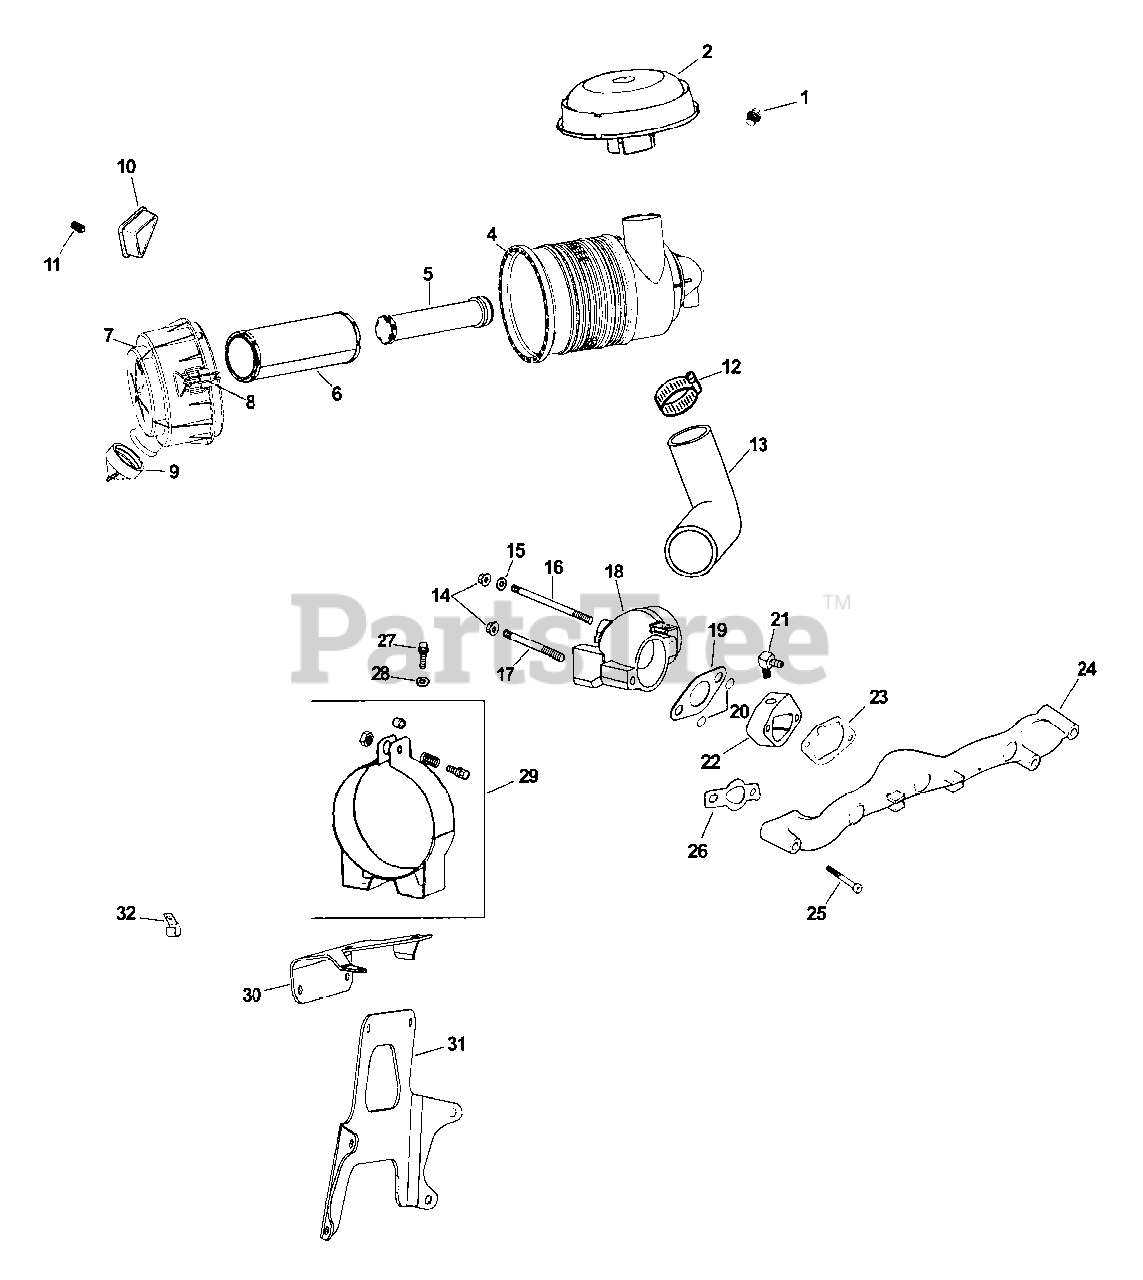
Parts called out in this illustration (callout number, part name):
2	Heavy Duty Air Cleaner Hood
4	Heavy Duty Air Cleaner Housing
5	Air Cleaner Element - Safety
6	Air Cleaner Element - Primary
7	Air Cleaner Cover Assembly
8	Clip
9	Dust Ejector Valve
10	Blower Housing Cover
11	Tapping Screw
12	Hose Clamp
13	Air Cleaner Hose
14	Hex Lock Nut (M6 x 1.0)
15	Copper Washer (1/4")
16	Stud (M6 x 1.0 x 180)
17	Stud (M6 x 1.0 x 40)
18	Elbow Adapter
19	Air Cleaner Adapter Gasket
21	Hose Connector
22	Remote Air Cleaner Adapter
23	Air Cleaner Base Gasket
24	Intake Manifold
25	Hex Flange Screw (M6 x 1.0 x 55)
26	Intake Manifold Gasket
27	Hex Flange Screw (M6 x 1.0 x 16)
28	Plain Washer (1/4")
29	Air Cleaner Bracket
30	Air Cleaner Mounting Bracket
31	Main Support Bracket
32	Cable Clip
